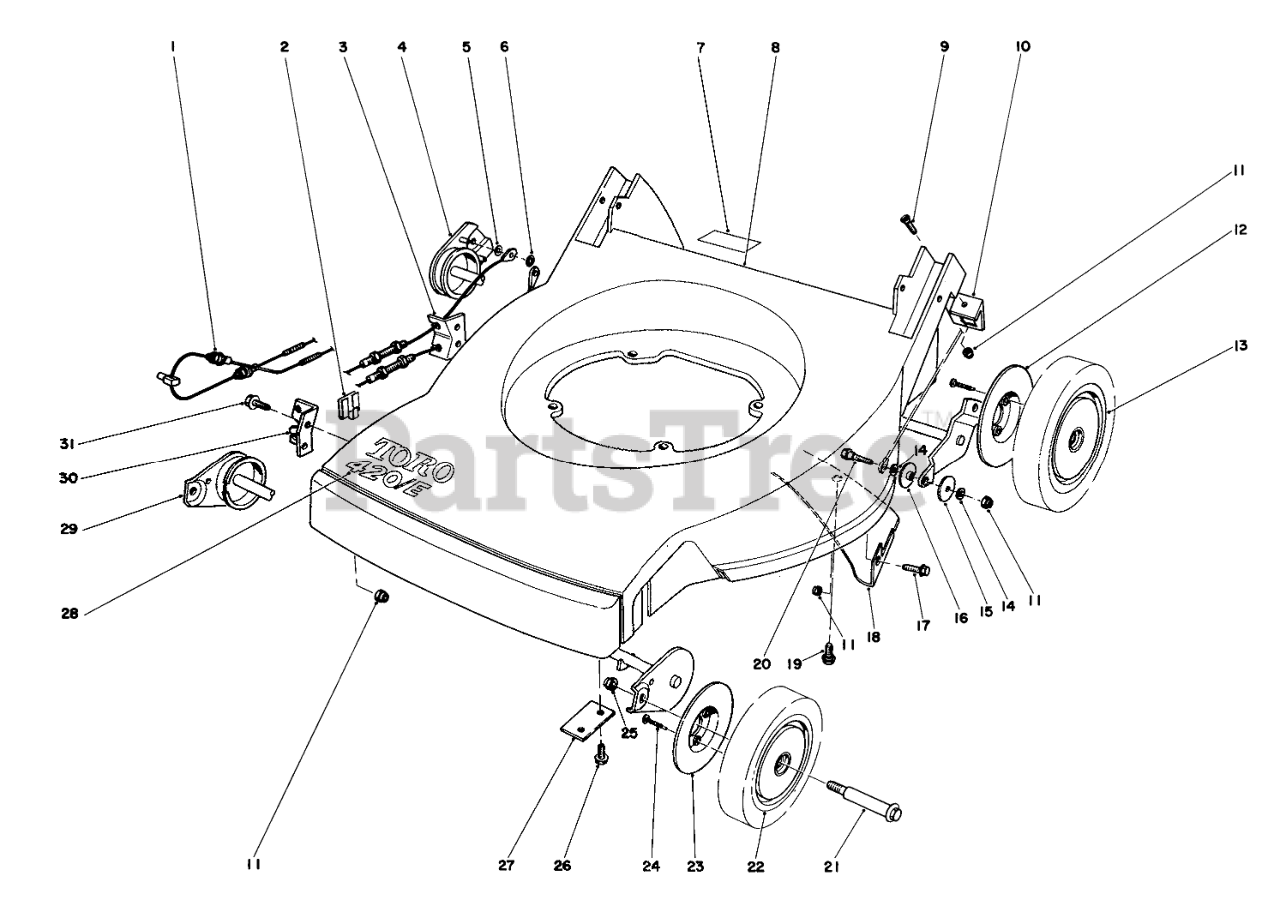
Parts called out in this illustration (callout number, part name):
1	HOC CABLE
2	Clip-Speed
3	Bracket-Rear Conduit
4	REAR AXLE WA
5	WASHER-FLAT
6	PUSH NUT
7	Decal Danger
8	Housing-42 cm
9	Screw-Flat Head Machine
10	CONTROL CABLE BRKT
11	M6 X 1 LOCKNUT
12	Wheel Cover Inner
13	Wheel and Tire Assembly 8"
14	WASHER-FLAT
15	Washer-Special
16	Bushing-Special
17	Capscrew-Hex Washer Head
18	Shield-Deck
20	Shoulder Screw-Cable
21	Wheel Bolt
22	Wheel and Tire Assembly 7"
23	Wheel Cover Inner
24	SCREW-DRIVE
26	THO FORM SCREW M6 X 1
27	Plate-Axle Mounting
28	Decal-Logo
29	Axle-Front
30	Bracket-Front Conduit
31	M6 X 1 HEX HD CAPSCRW
